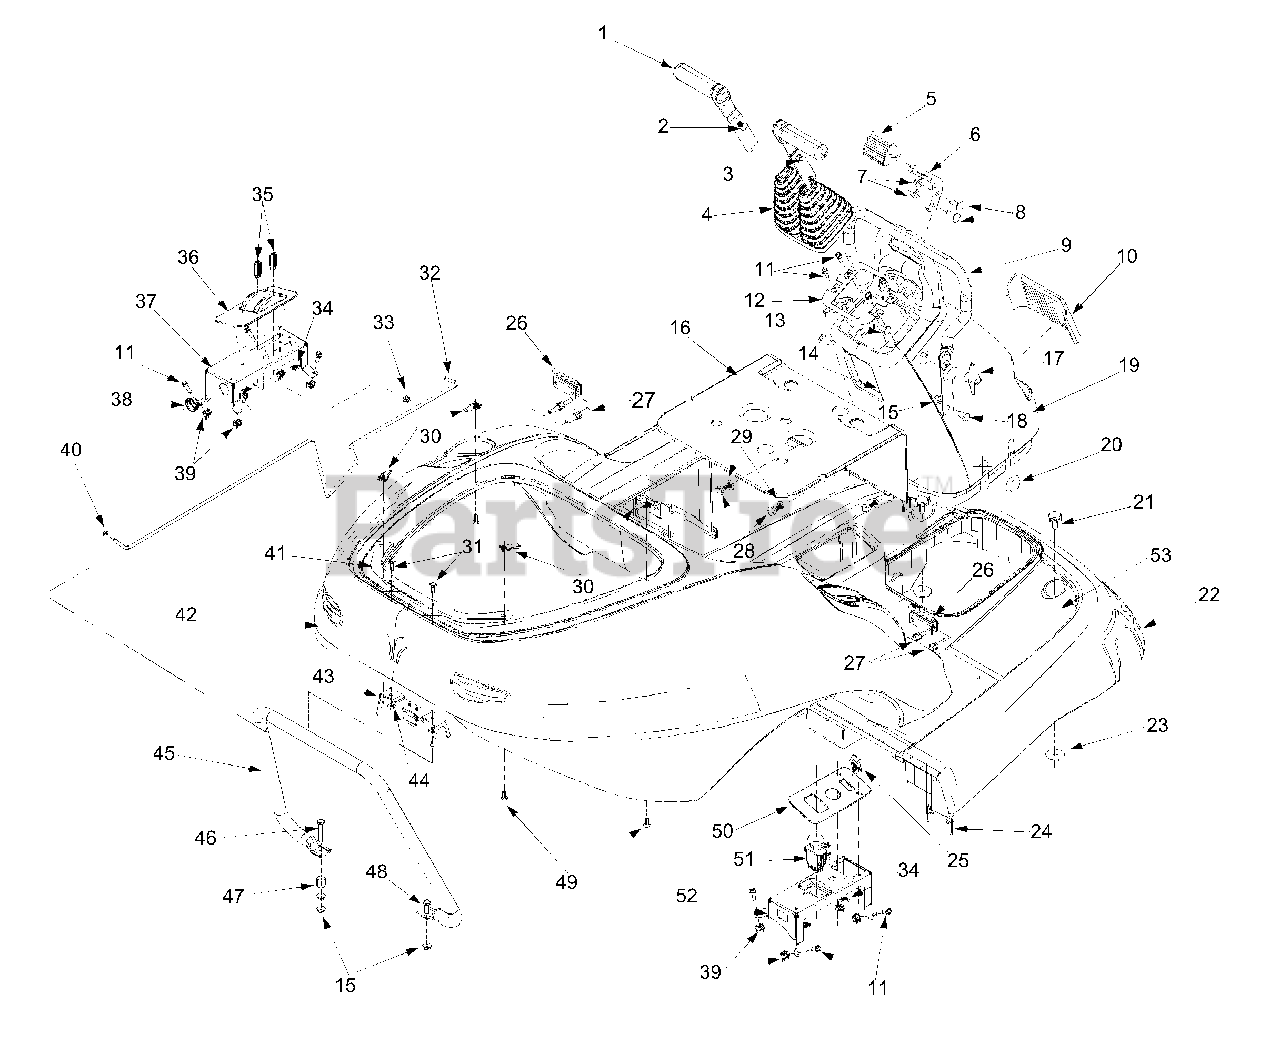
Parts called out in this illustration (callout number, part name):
1	Control Handle
2	Carriage Bolt 5/16-18 x .75
3	Flange Lock Nut 5/16-18
4	Control Bellow
8	Carriage Bolt 3/8-16
11	Hex Washer Screw 1/4-20 x .75
16	Seatbase Cover
17	Wingnut Knob Assembly 5/16-18
18	Shoulder Screw
21	Shoulder Screw 3/8-16 x .75
23	Flat Washer .406 ID x 1.5 OD
24	Body Plate Assembly
25	Key
27	Hex Cap Screw 5/16-18 x 1.0
28	Shoulder Screw
29	Flat Washer .474 ID x .879 OD
30	U-Type Nut 1/4-20
31	Hex Cap Screw 1/4-20 x .75
33	Clip
34	Push Nut
36	Control Panel Cover - LH
39	Retainer Nut 1/4-20
41	Latch Mounting Plate
43	Clip Spring Bracket Assembly
44	Lock Nut 1/4-20
48	Hex Cap Screw 5/16-18 x 1.0
49	Screw 1/4-20 x .625
50	Cover Panel - RH
51	Electric Switch PTO
